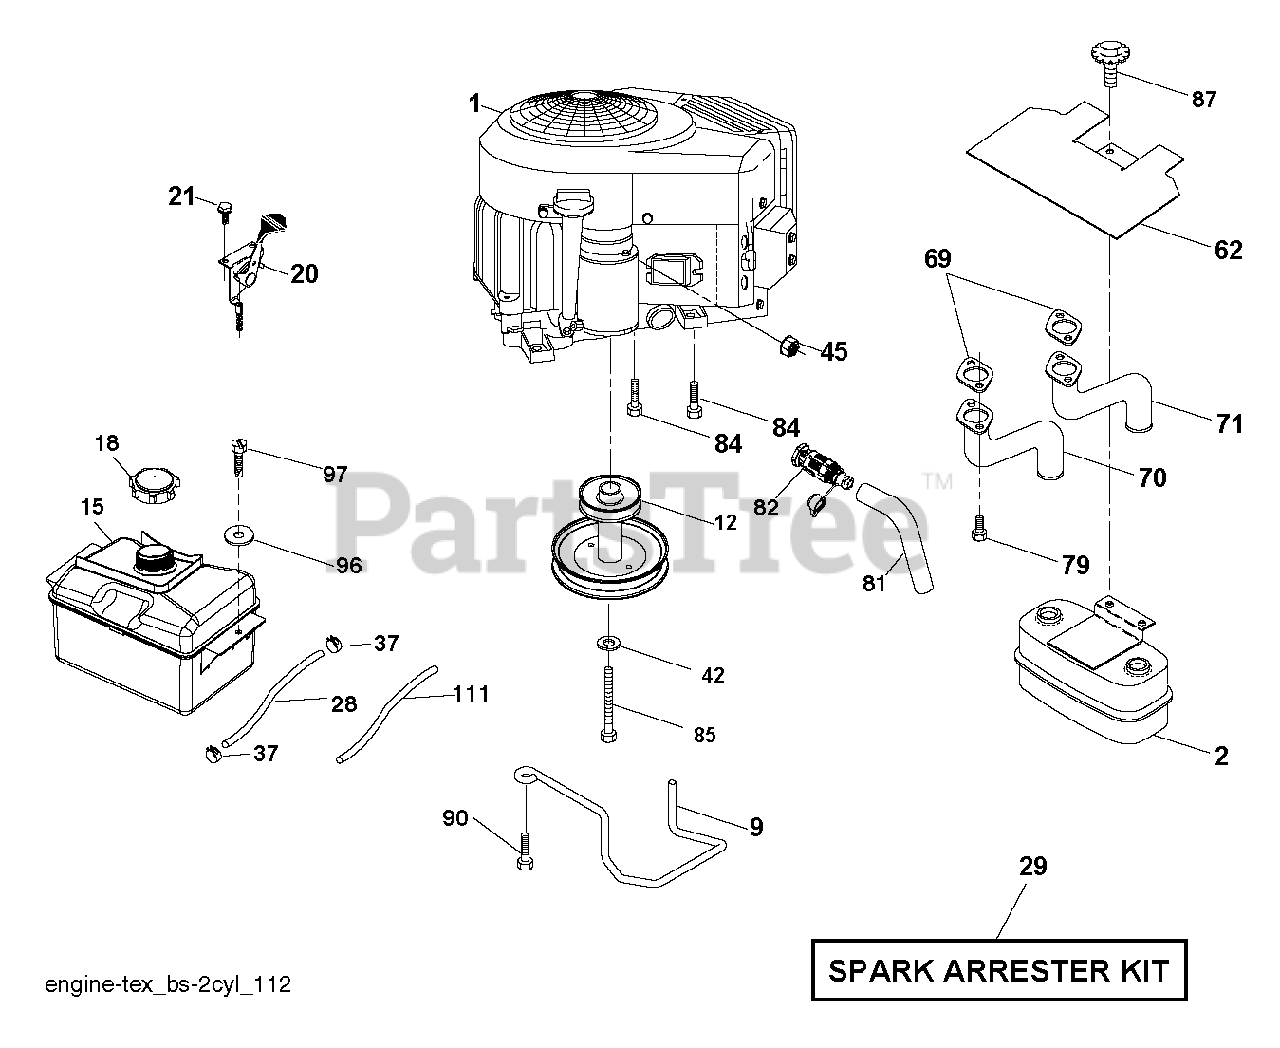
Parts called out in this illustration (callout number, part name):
2	MUFFLER.TWIN.CYL.LOW.TONE
9	KEEPER.BELT.ENGINE
12	PULLEY.ENGINE.5.0.PD
15	TANK.ASM.FRT.2.5 GAL.W/CAP.EPA
18	CAP.FUEL.2 WAY VENT
20	CONTROL.TH/CK.COBRA.B&S.TWN.
21	SCREW.#10 X 0.750.BOS (2 2)
28	LINE.FUEL.20"FRONT.EMI
29	KIT.SPARK ARRESTOR(392390 B&S)
37	HOSE CLAMP
42	LOCKWASHER
45	NUT
62	SHIELD.HEAT.MUFFLER
70	EXHAUST.TUBE.LH.BS/TWIN
71	EXHAUST.TUBE.RH.B&S.TWIN.INTEK
79	SCREW.SOCKET.HEAD.5/16-18
81	TUBE, DRAIN OIL ASM.
82	VALUE.OIL.DRAIN
84	SCREW.3/8-16
85	BOLT HEX 7/16-20X4-1/4"
87	BOLT, 5/16-18 X 1 3/4
90	SCREW 3/8-16X1
97	SCREW HEXWSHR 1/4-20X3/4
111	RP PURGE LINE
